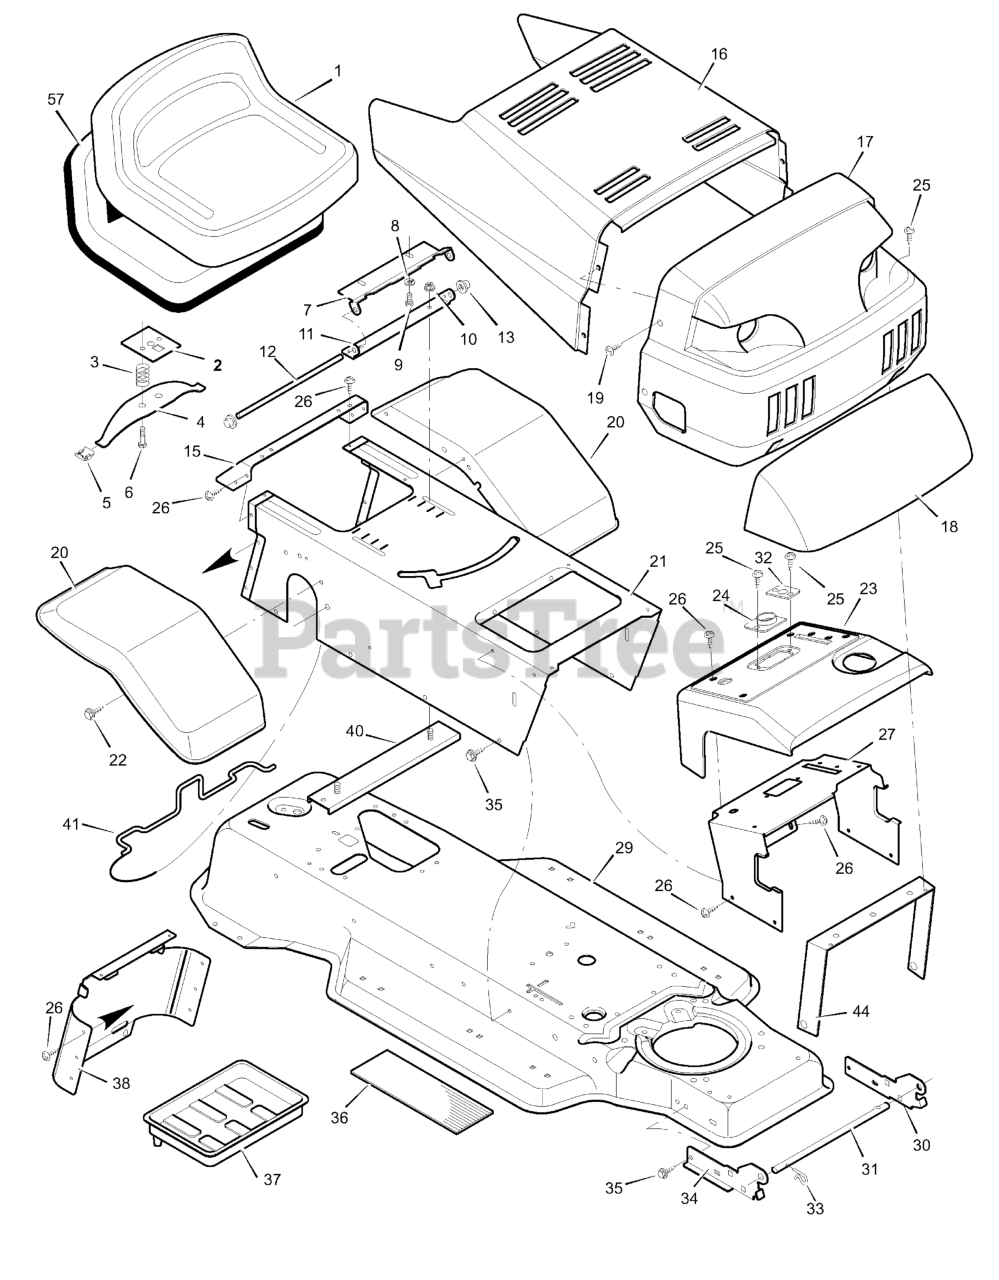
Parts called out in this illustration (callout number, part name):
2	Plate Assembly, Switch
3	Spring, Compression
4	Spring, Seat
5	Glide, Spring
6	Bolt, Shoulder
7	Support, Seat
8	Lockwasher
9	Bolt, Hex
10	Locknut, Flange
11	Bracket, Pivot
12	Rod, Pivot
13	Cap, Push On
15	Fender, Apron
17	Grille Assembly
21	Console Assembly
23	Dash Panel
24	Bearing, Steering
26	Screw
27	Support, Dash
29	Frame Assembly
30	Bracket, Left Grille
31	Rod, Pivot
32	Bearing
33	Pin, Hair
34	Bracket, Right Grille
37	Tray, Battery
38	Cap, Console
39	Bolt
40	Channel Assembly
41	Clamp, Battery
44	Brace, Grille
57	Pan, Seat (with foam)
